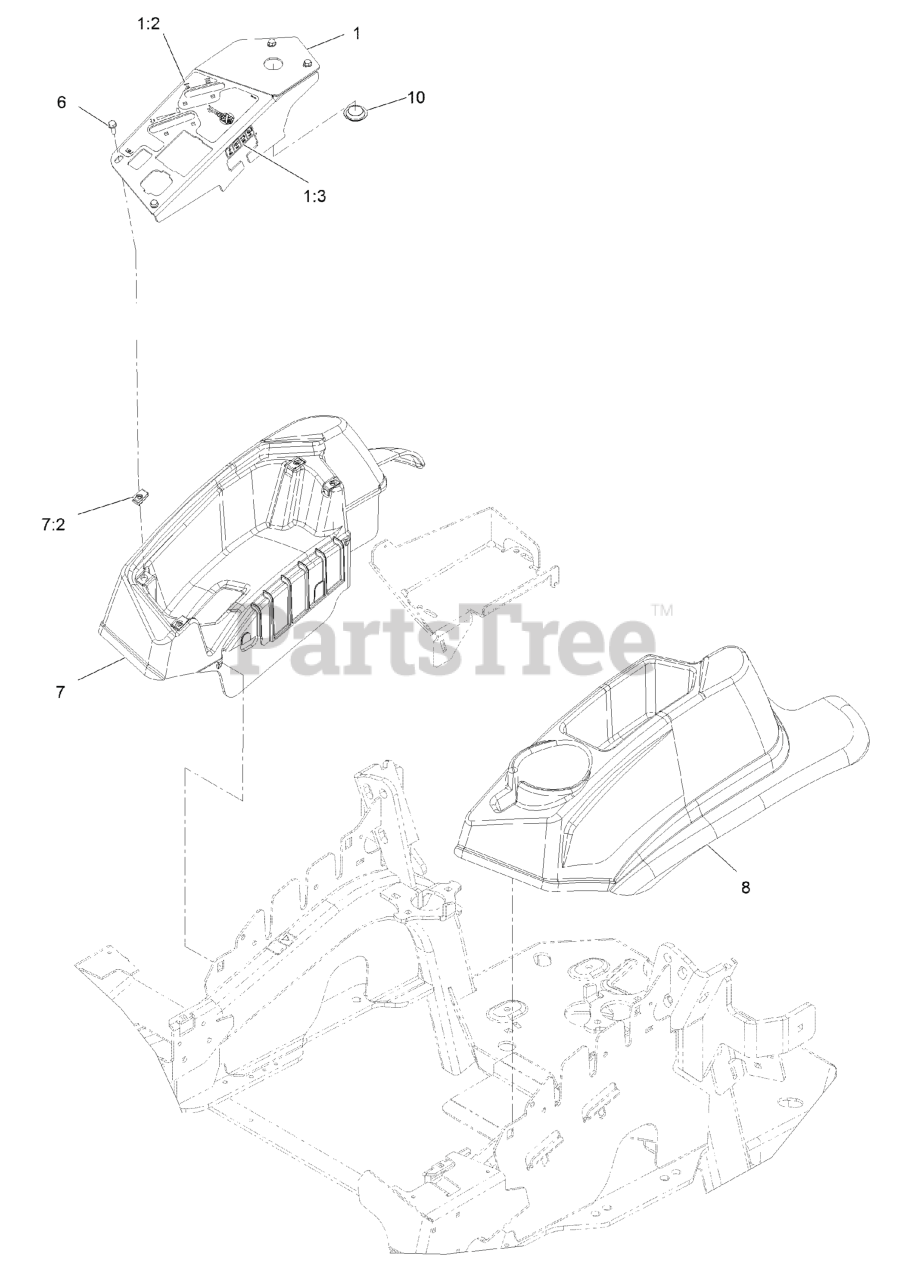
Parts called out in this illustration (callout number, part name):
1	CONSOLE,PANEL W/DECAL
1:2	DECAL-CONTROL PANEL NON-E
1:3	DECAL-FUSES
2	ASM, CHOKE CABLE
3	ASM,THROTTLE CABLE
4	BOLT-CARR
5	NUT-LOCK, NI
6	SCREW-HWH
7	CONSOLE,RH AS ASM
8	CONSOLE, LH AS
9	CLAMP-HOSE
10	PLUG-PLASTIC
